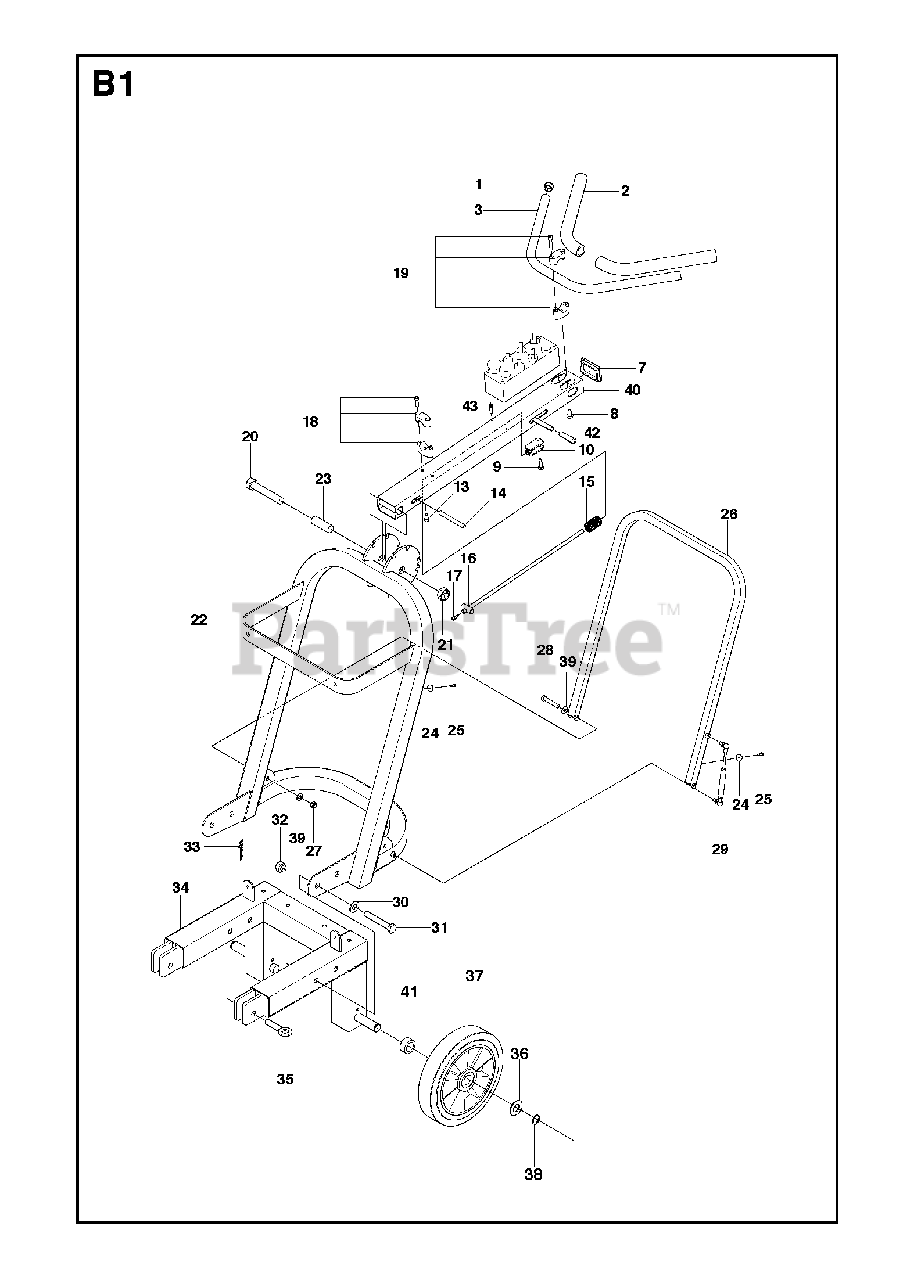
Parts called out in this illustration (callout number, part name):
1	EMBOUT REF 320 GL 25/
27	HEXAGON LOCKING NUT
33	SPRING COTTER
39	WASHER
